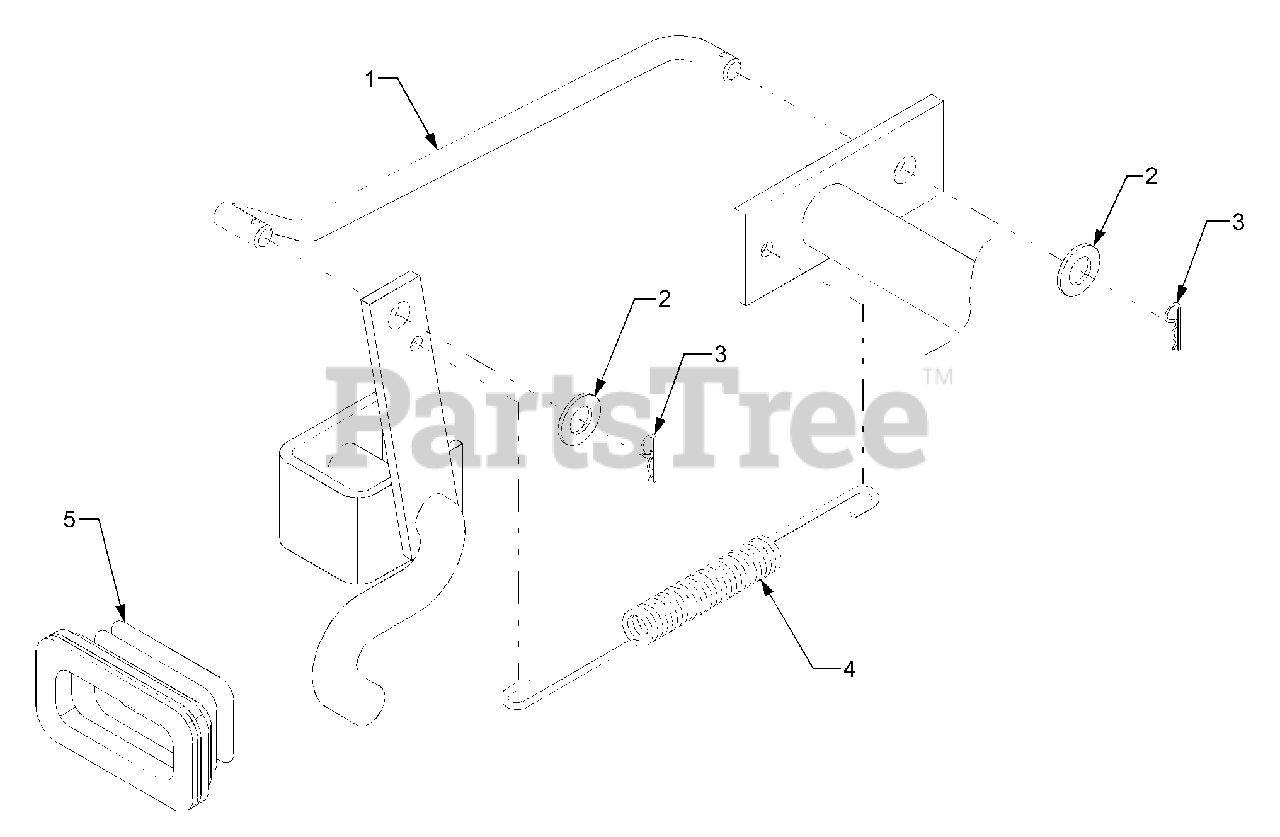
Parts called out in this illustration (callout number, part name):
1	Rod, Differential
2	Washer, Plain
4	Spring, Differential
